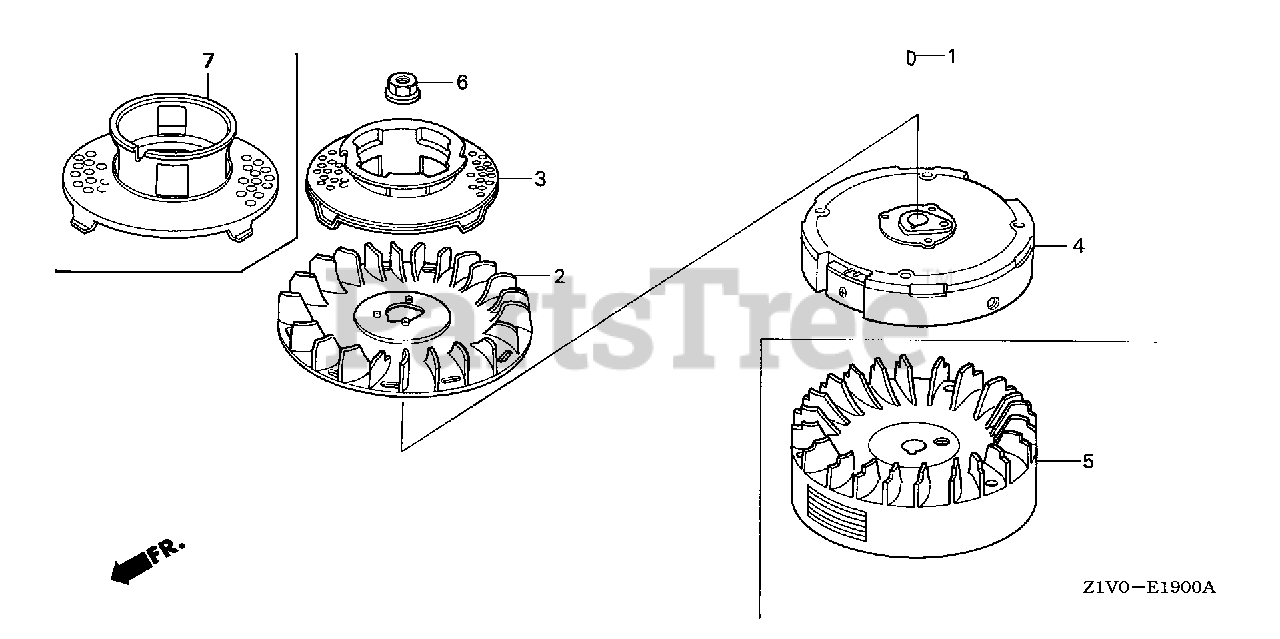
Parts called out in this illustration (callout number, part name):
1	KEY, SPECIAL WOODRUFF (25X18)
3	PULLEY, STARTER
5	FLYWHEEL (BRAKE)
6	NUT, SPECIAL (14MM)
7	PULLEY, STARTER
